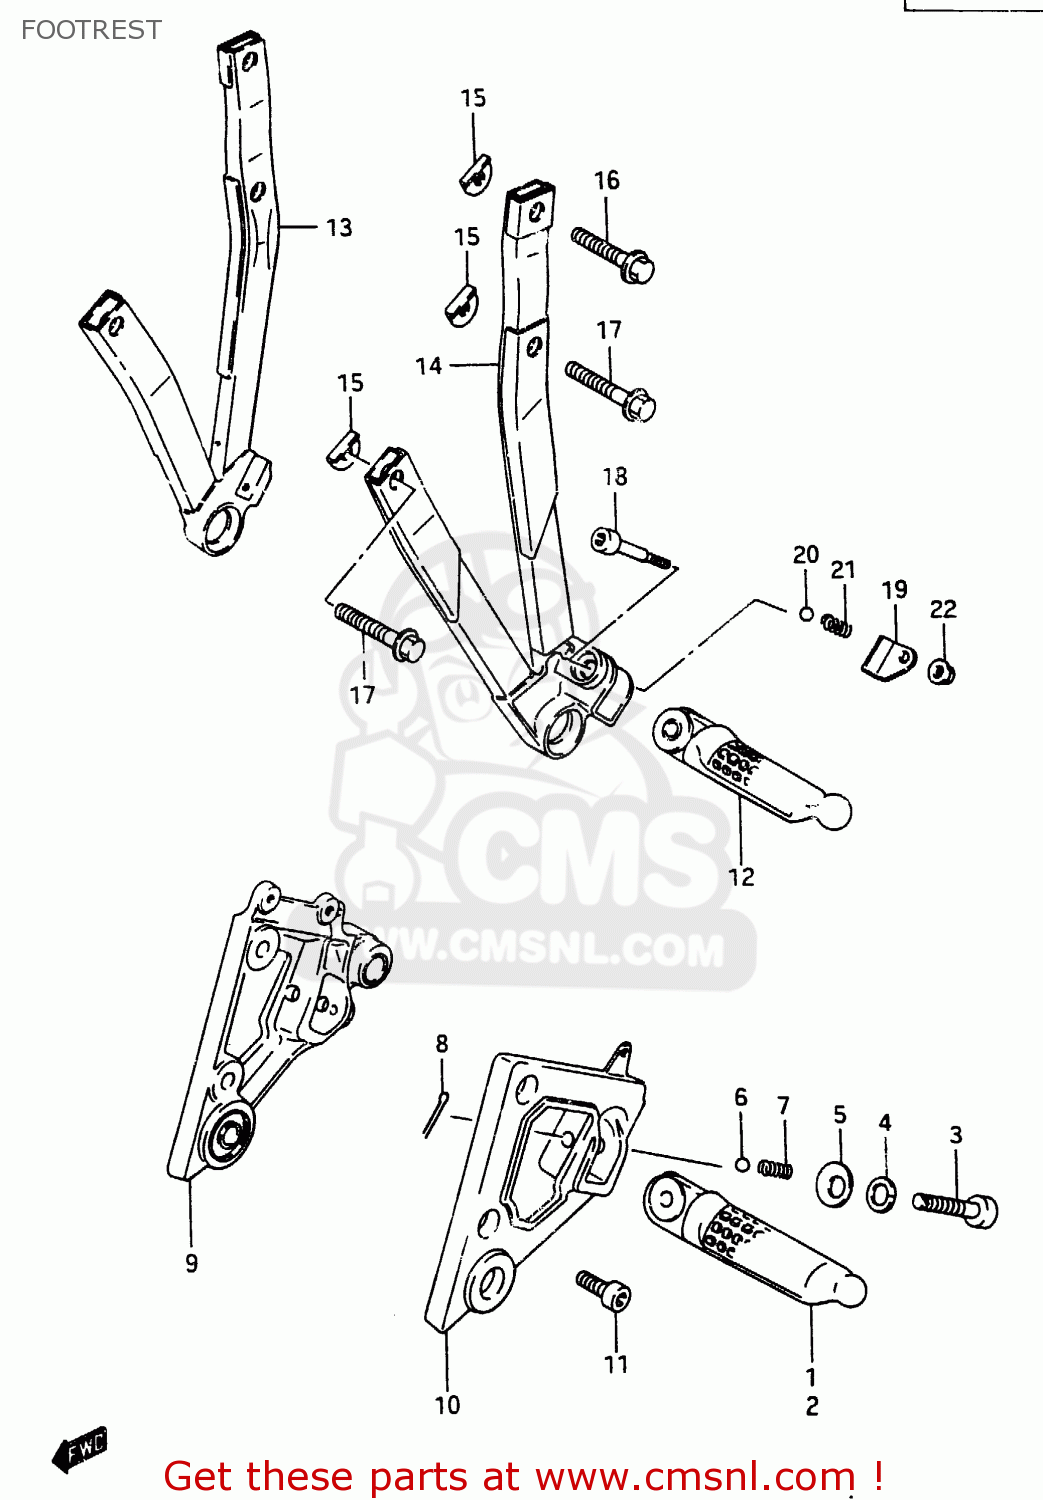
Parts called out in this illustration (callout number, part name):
1	FOOTREST ASSY,FR,R
2	FOOTREST ASSY,FR,L
3	BOLT, FRONT FOOTREST
4	WASHER,LOCK
5	PLATE,SPRING STOP FR
6	BALL
7	SPRING
8	PIN
9	BRACKET, MUFFLER RH
10	BRACKET COMP,MUFFLER,L
11	BOLT
12	FOOTREST ASSY
13	BRACKET, PILLION FOOTREST RH
14	BRACKET, PILLION FOOTREST LH
16	BOLT
17	BOLT (8X40)
18	BOLT,PILLION FOOTREST
19	PLATE,SPRING STOP LH
20	BALL
21	SPRING
22	NUT
